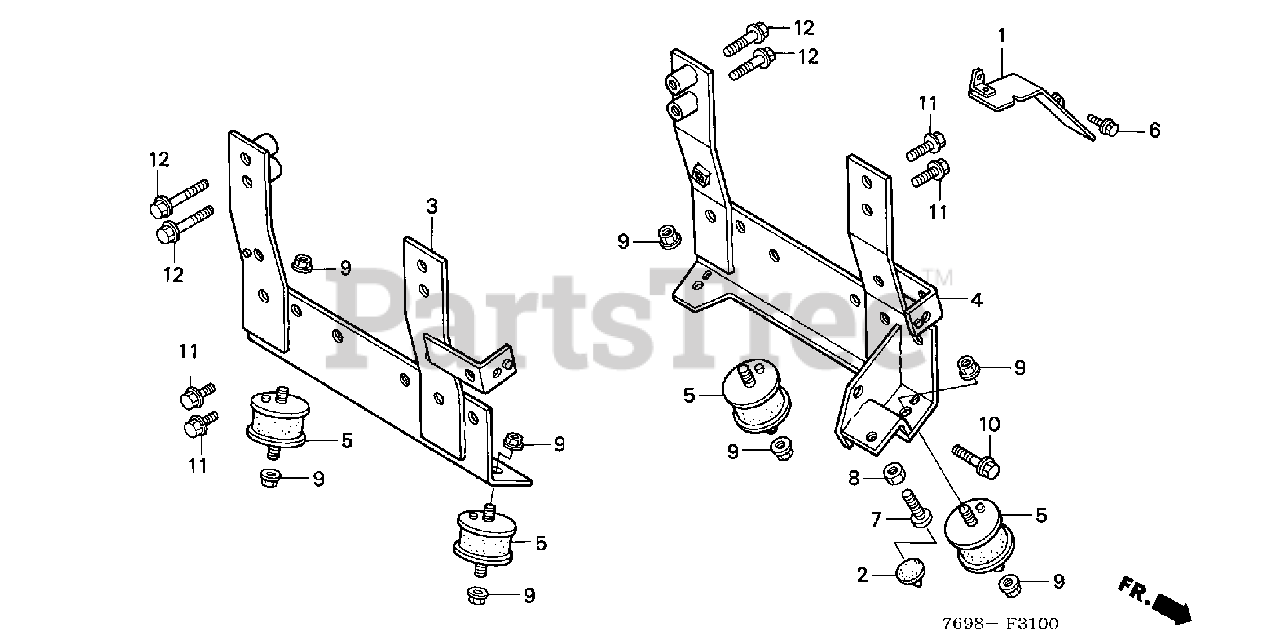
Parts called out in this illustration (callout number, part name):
1	COVER, FLYWHEEL
2	PAD, PEDAL STOPPER
3	BRACKET, R. ENGINE MOUNT
4	BRACKET, L. ENGINE MOUNT
5	RUBBER, ENGINE MOUNTING
6	BOLT, FLANGE (6X14)
7	BOLT, STOPPER (12X26)
8	NUT, HEX. (12MM)
9	NUT, FLANGE (10MM)
10	BOLT, FLANGE (8X22)
11	BOLT, FLANGE (10X25)
12	BOLT, FLANGE (10X45)
